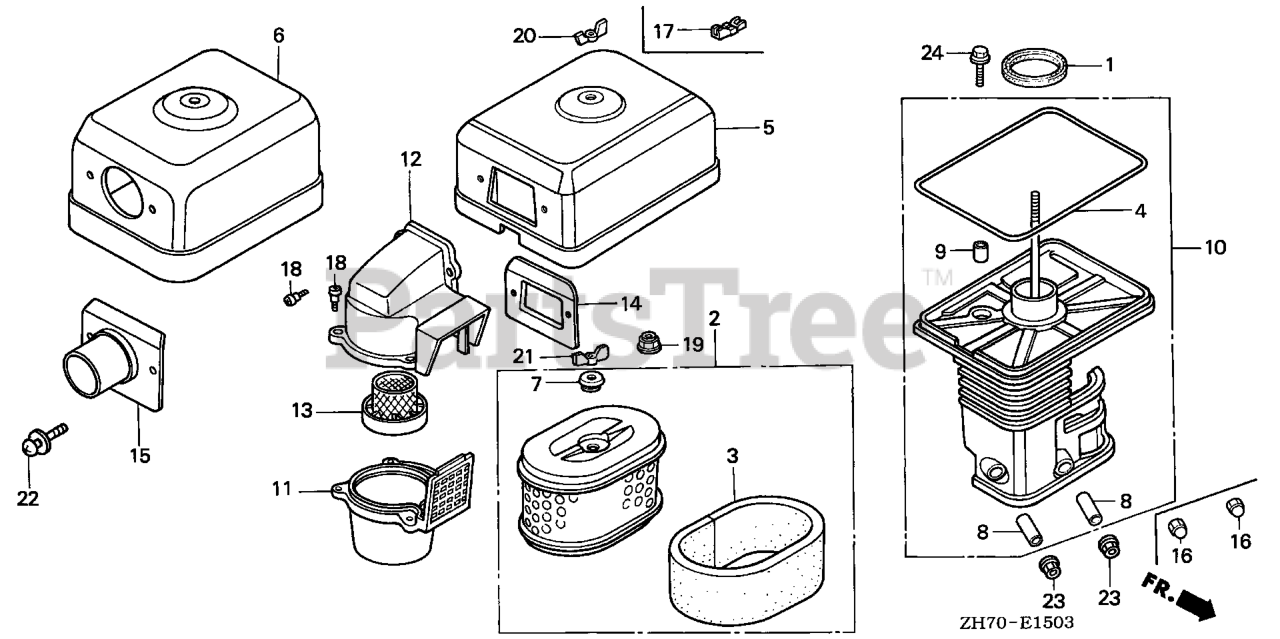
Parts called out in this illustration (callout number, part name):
1	GASKET, ELBOW
2	ELEMENT, AIR CLEANER (DUAL) Use up to Engine SN 2115700.
2	ELEMENT, AIR CLEANER (DUAL)
3	FILTER (OUTER)
4	GASKET, AIR CLEANER COVER
5	COVER, AIR CLEANER (DUAL)
7	GROMMET, AIR CLEANER
8	COLLAR, AIR CLEANER
9	COLLAR B, AIR CLEANER
10	ELBOW, AIR CLEANER
11	CASE, PRE AIR CLEANER
12	CAP, PRE AIR CLEANER
13	GUIDE, PRE AIR CLEANER
14	PLATE, PRE AIR CLEANER
16	NUT, CAP (6MM)
17	WINGNUT, AIR CLEANER COVER
17	WINGNUT (6MM)
18	BOLT, MUDGUARD
20	WINGNUT, TOOL BOX SETTING
21	WINGNUT, TOOL BOX SETTING
23	NUT, FLANGE (6MM)
24	BOLT, FLANGE (6X20)
